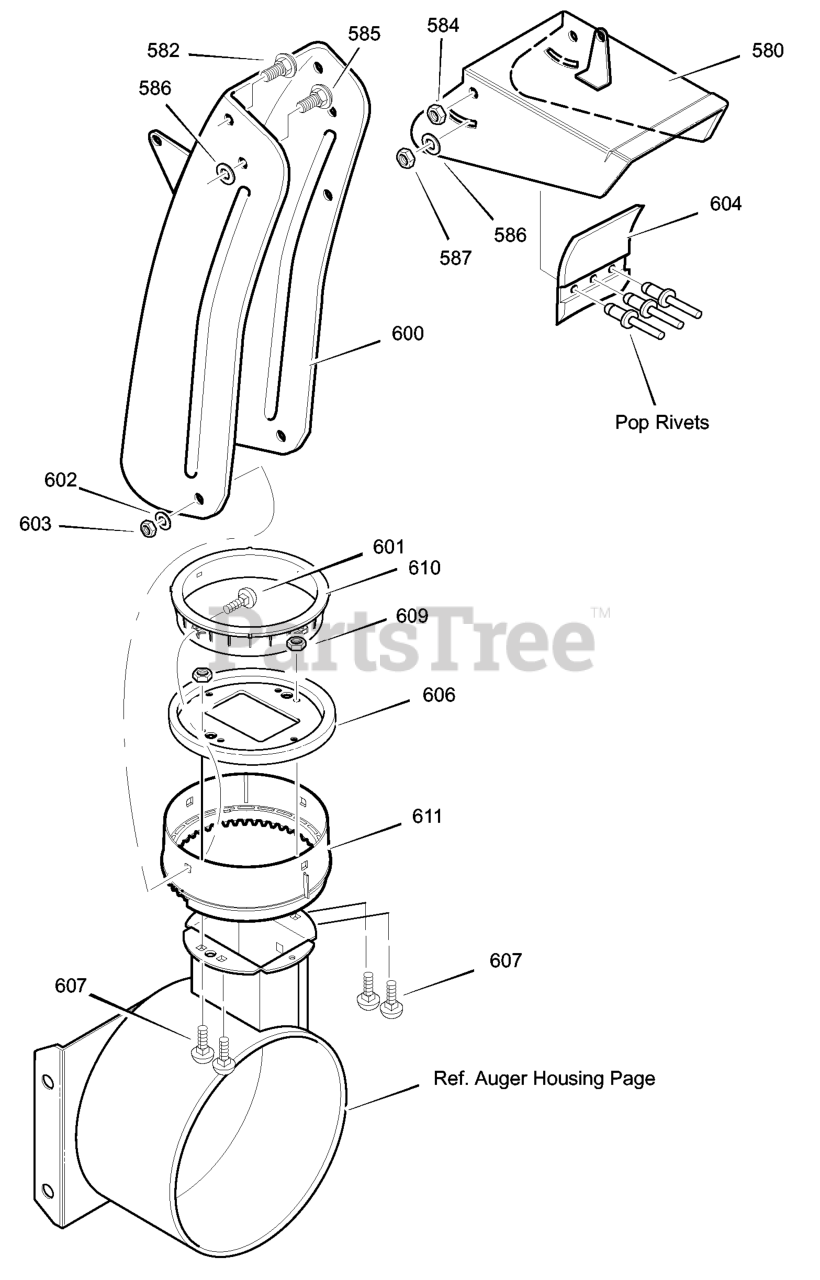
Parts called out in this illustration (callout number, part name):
580	CHUTE, UPPER W/REMOTE
582	SCREW, 5/16-18 x 0.75
584	NUT
585	SCREW, 5/16-18 x 0.75
586	PLASTIC WASHER
587	NUT
600	CHUTE, LOWER W/REMOTE
602	WASHER, FLAT
603	NUT
606	CHUTE COLLAR
607	BOLT
609	NUT
610	RETAINER, RING INNER
611	RETAINER, RING OUTER
